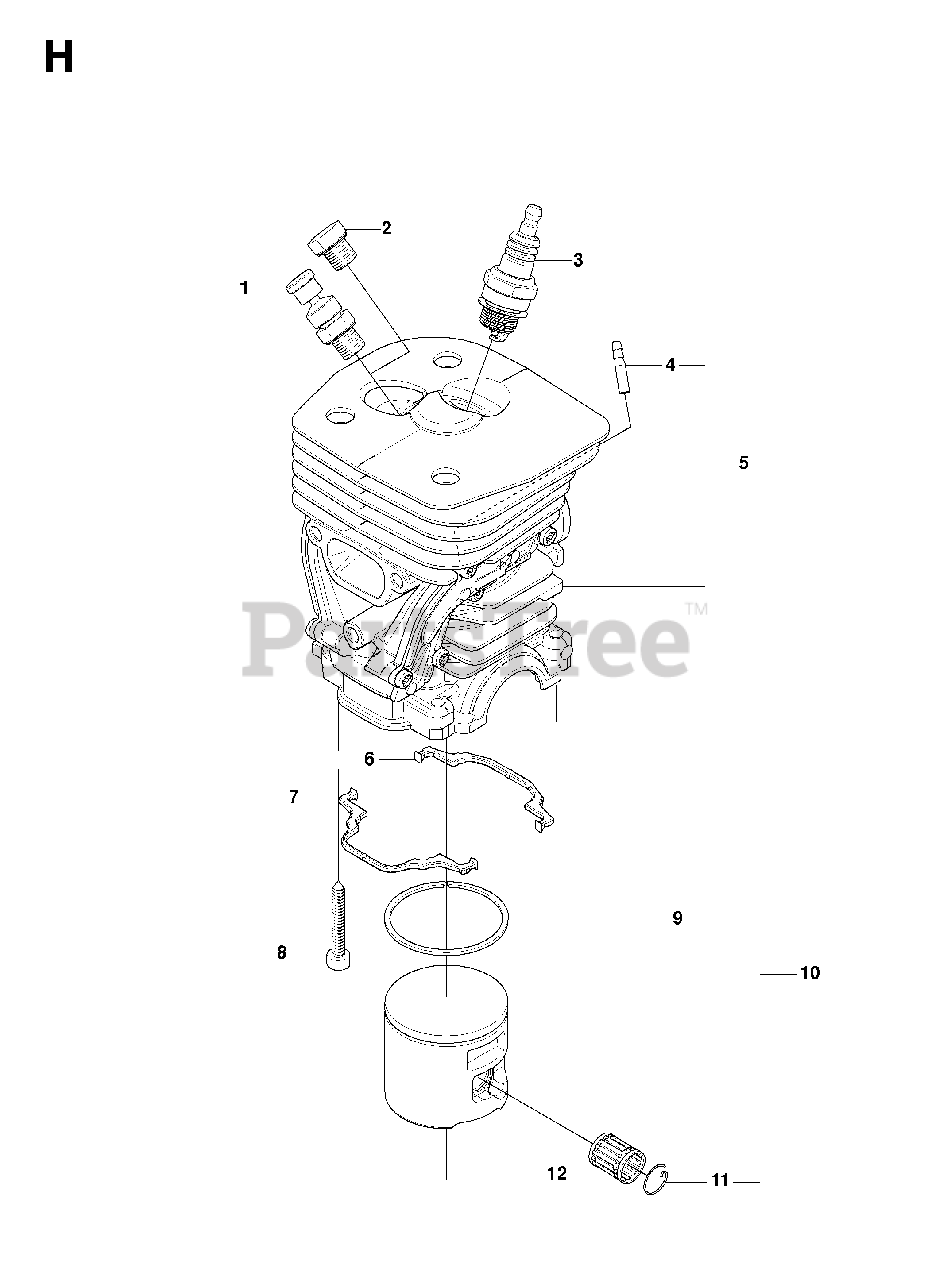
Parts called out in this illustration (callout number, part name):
2	CYLINDER PLUG
3	SPARK PLUG RCJ7Y
9	PISTON RING
10	PISTON CPL.
12	SUPPORT BUSHING
